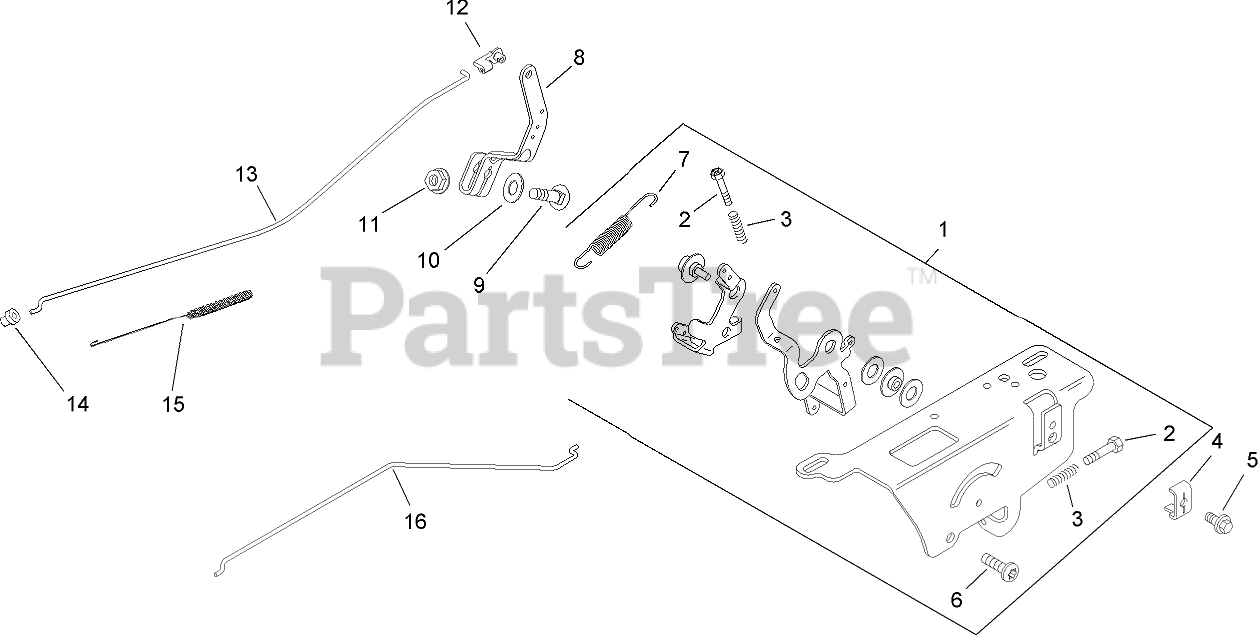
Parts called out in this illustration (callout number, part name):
1	Speed Control ASM (Includes2-3, 6-7)
2	Screw-Thread Forming (M4x0.7x25)
3	Spring-Control, Speed
4	CLAMP-CABLE
5	SCREW-FLANGE, THREAD FORMING (M5X0.8X16)
6	Screw-Socket, 6 Lobed (Thread Forming, M6x1.0x20)
7	Spring-Governor
8	Lever-Governor
9	Bolt-Square Neck, Round Head (1/4-20x1)
10	Washer-Lock, Internal Tooth (1/4)
11	Nut-Flange, Hex (1/4-20)
12	BUSHING-RETAINING, LINKAGE
13	Linkage-Throttle
14	BUSHING-LINKAGE, THROTTLE
15	Spring-Linkage
16	Linkage-Choke (Single Wire)
